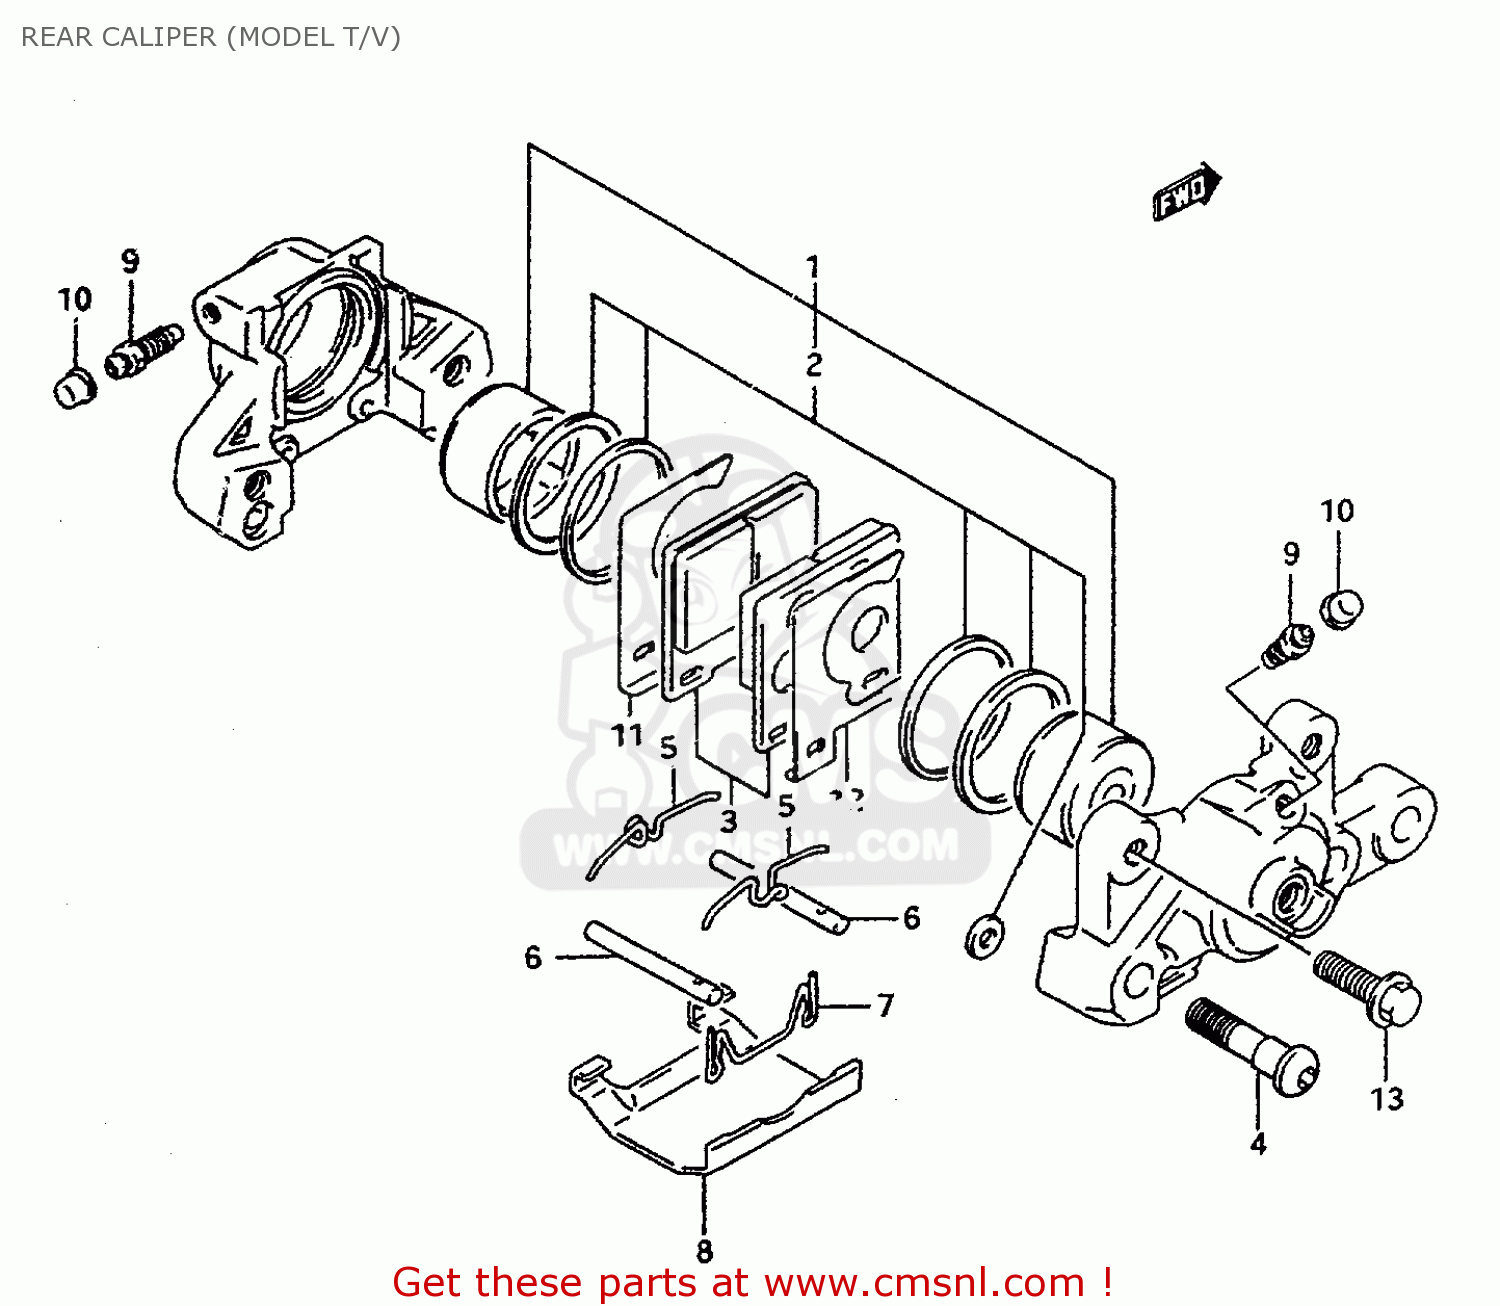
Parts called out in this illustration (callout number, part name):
00000	CALIPER ASSEMBLY,REAR
1	PISTON SET
2	SEAL SET,PISTON
3	PAD SET (NAS)
4	BOLT,HOUSING
5	SPRING
6	PIN,PAD
7	CLIP,PAD PIN
8	COVER
9	BLEEDER
10	CAP,BLEEDER PLUG
11	SHIM,INNER
12	SHIM,OUTER
13	BOLT
16	SPACER,REAR CALIPER
17	BOLT(8X35)
18	WASHER (8.2X22X3.2)
